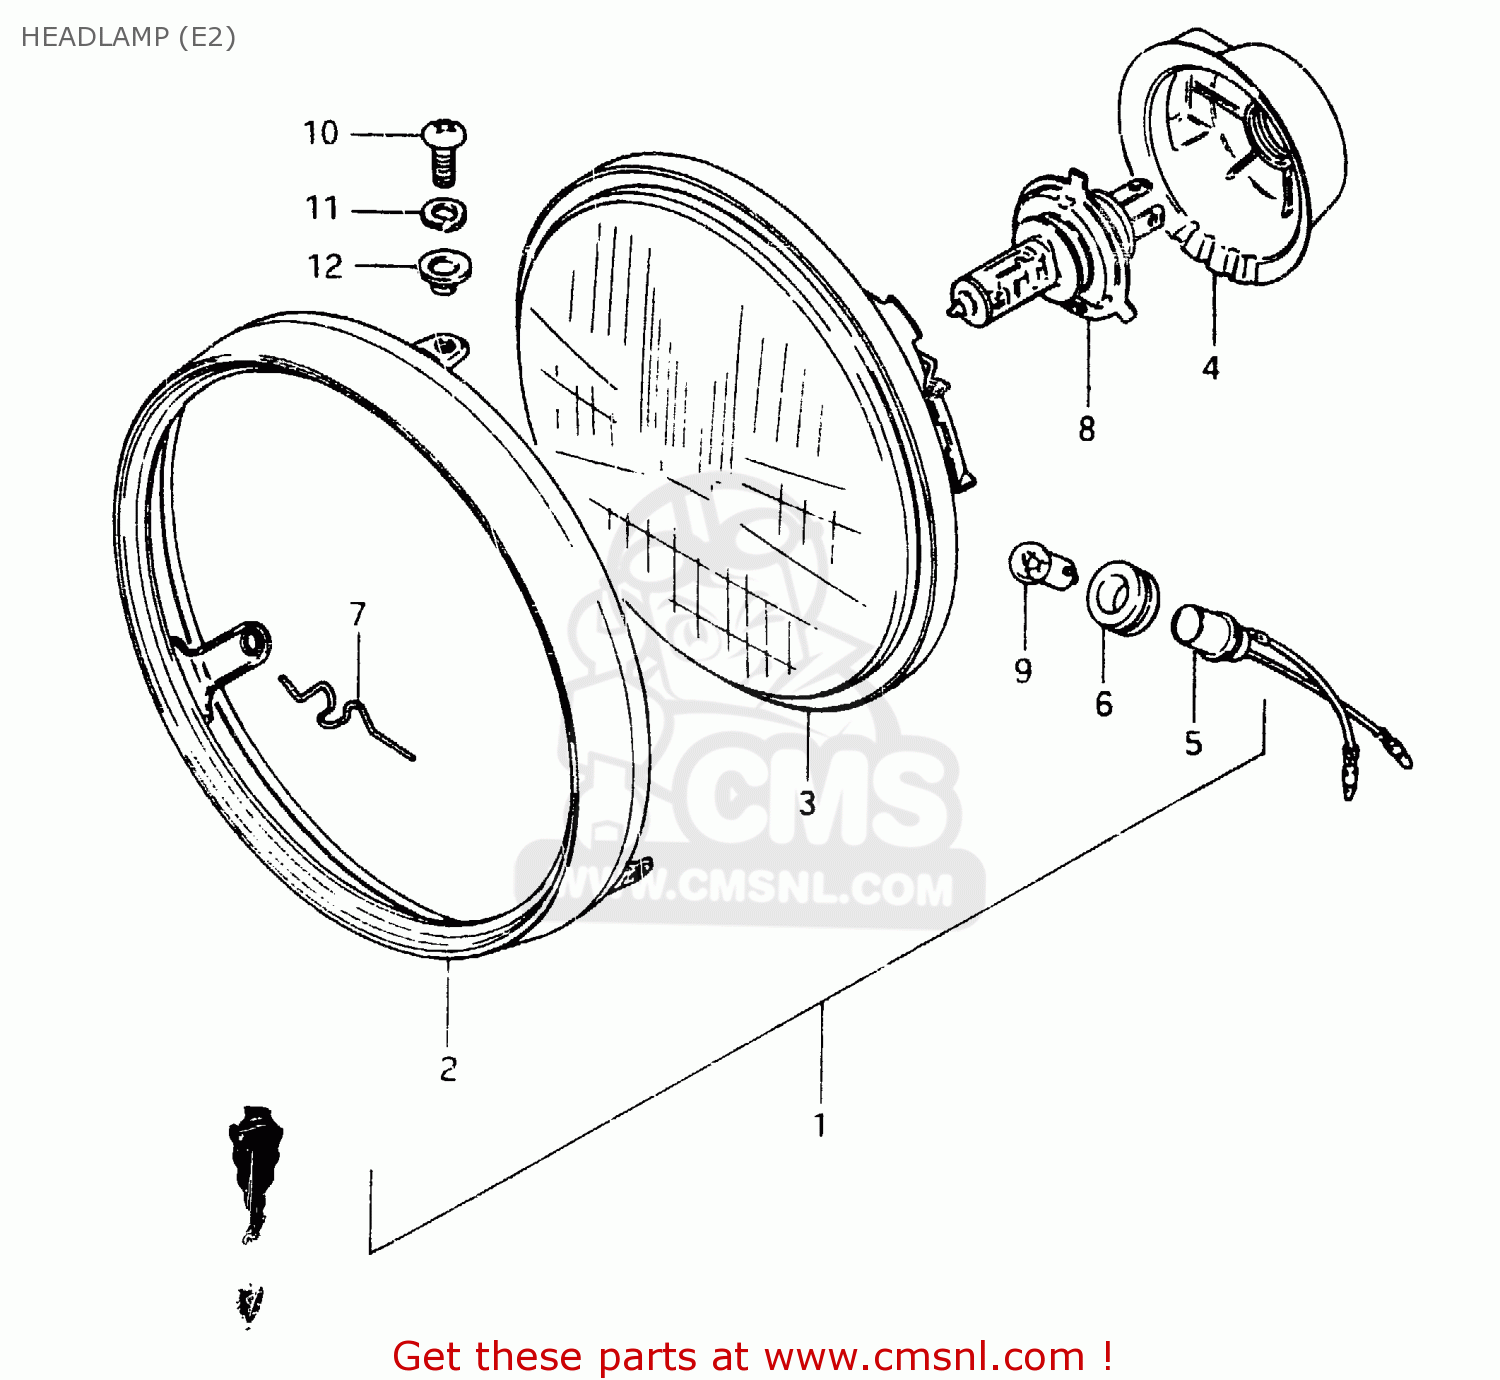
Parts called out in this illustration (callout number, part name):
1	HEADLAMP ASSY
2	RIM
3	LAMP UNIT
4	COVER,SOCKET
5	SOCKET
6	JOINT,RUBBER
7	SPRING
8	BULB(12V60/55W,H4)
9	BULB(12V3.4W,STANLEY,A72A)
10	SCREW
11	WASHER,LOCK
12	WASHER
